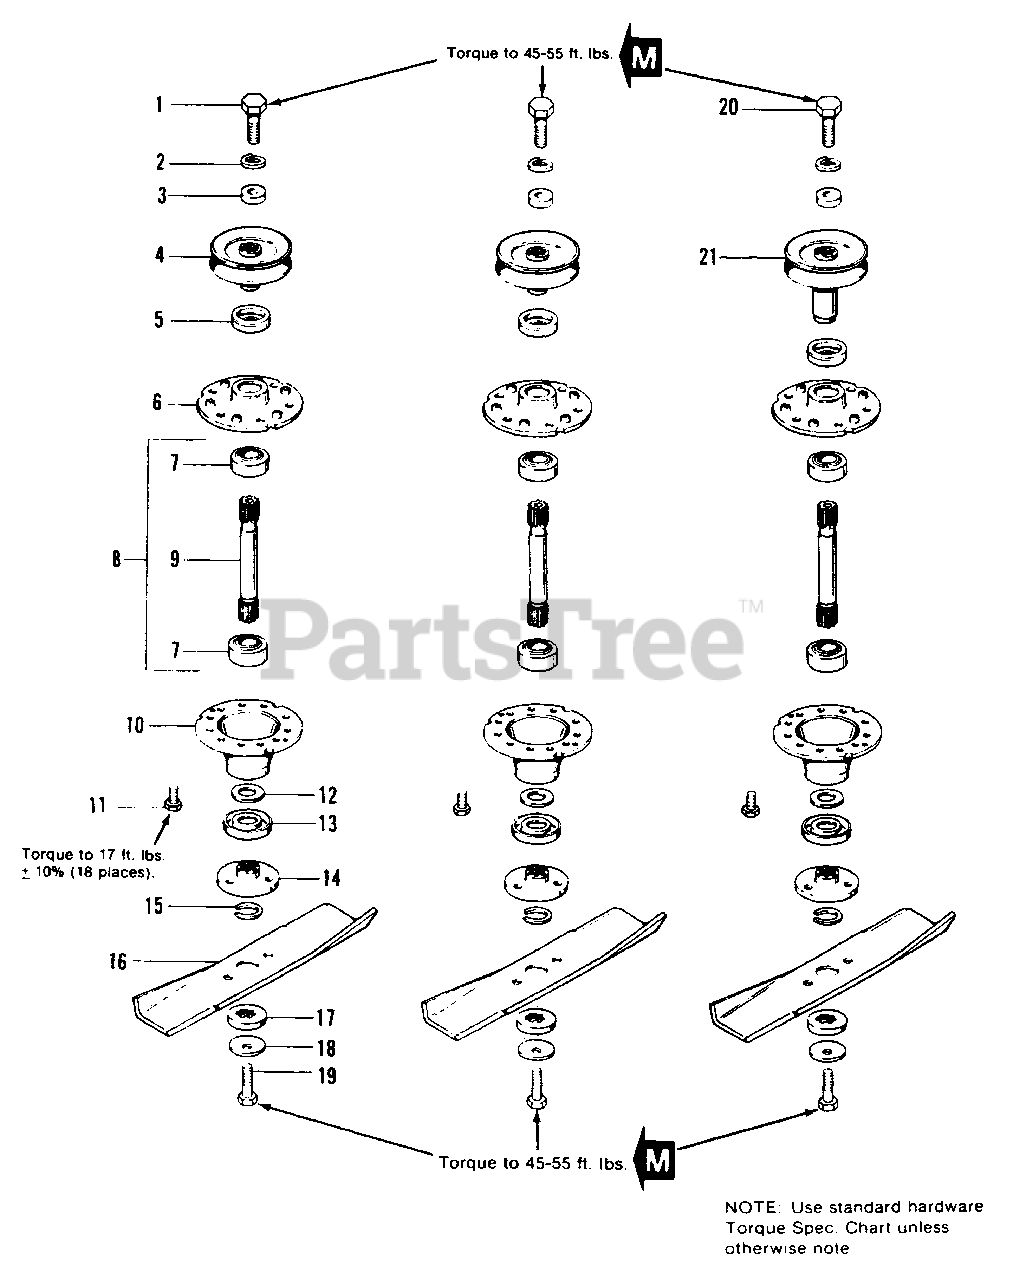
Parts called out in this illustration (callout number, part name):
1	CAPSCREW, Hex, 7/16-14 x 1-1/2
2	LOCKWASHER, 7/16
3	WASHER, Plain, 29/64 x 1-1/4 x 1/4
4	PULLEY ASSY.
5	SHIELD, Bearing Upper, Arbor
6	HOUSING TOP
8	SHAFT & BEARING ASSY.
10	HOUSING, Bottom
11	SCREW, Hex, Taptite, 5/16-18 x 3/4
12	WASHER, Shim
13	SHIELD, Grass
14	BLADE, Adapter
15	RING, Self Locking
16	BLADE, 48" Mower
16	BLADE, 42" Mower
17	WASHER, Spline
18	WASHER, Spring
19	CAPSCREW, Hex, 7/16-14 x 1
20	CAPSCREW, Hex, 7/16-14 x 3-1/2
21	PULLEY ASSY
